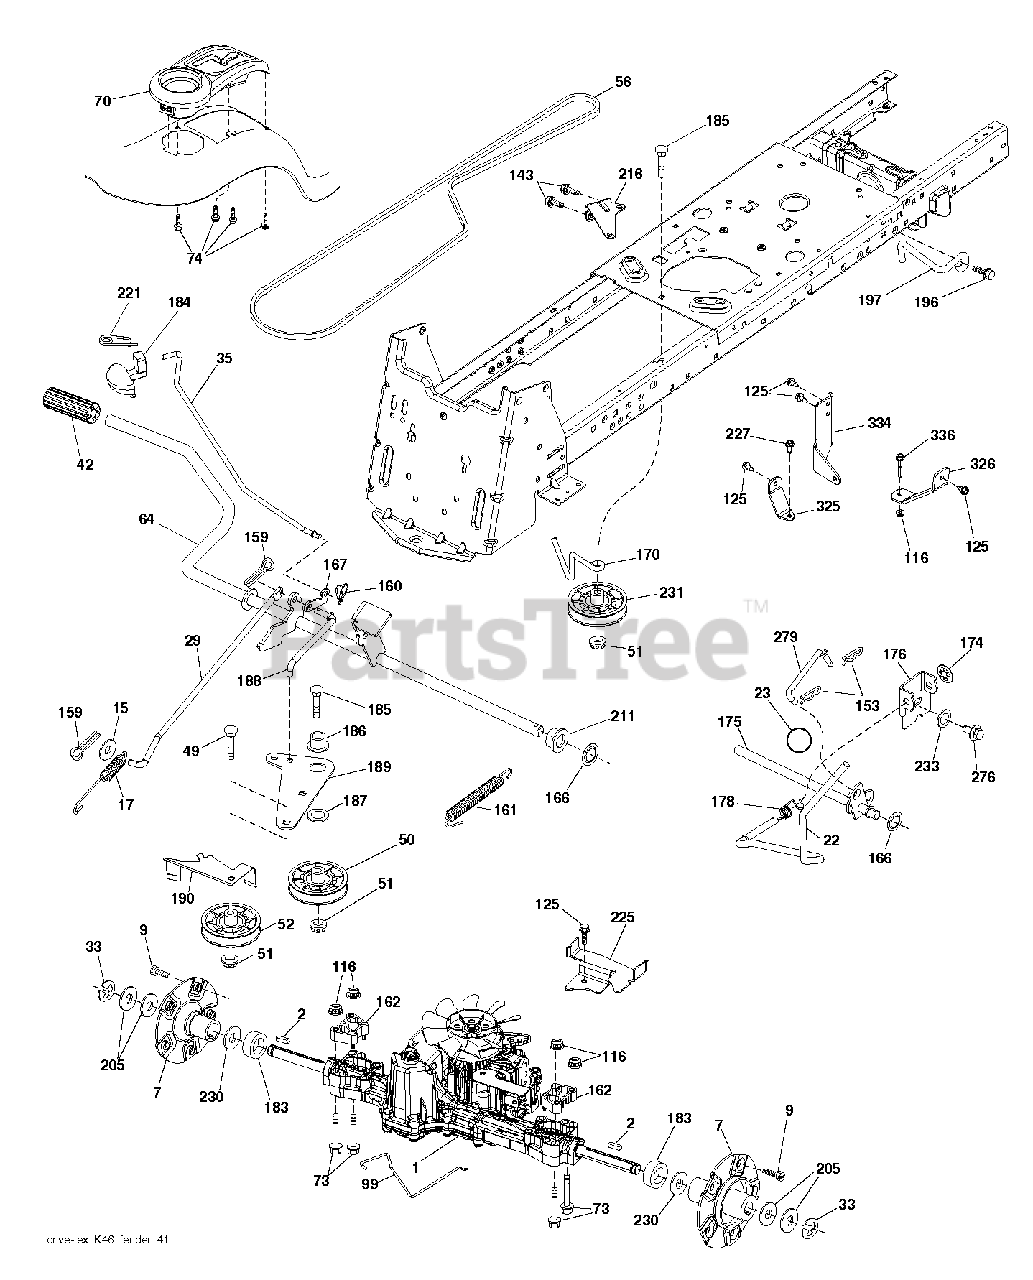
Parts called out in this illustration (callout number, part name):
2	KEY.SQUARE.187X2.500
7	HUB.ASM.WHEEL.REAR.22"
17	SPRING.BRAKE.K46.GREEN
22	ROD.SHIFT.FENDER.STGT.
23	KNOB.DELUXE.(PISTOL.GRIP).BLAC
29	ROD.BRAKE.K46
33	E-RING LT
35	Parking Brake Rod, GT Husq
42	PEDAL COVER T
49	BOLT
50	IDLER.FLAT.910.OFFSET
51	NUT LOCK FLG 3/8-16 UNC
52	IDLER.V-GROOVE.910.OFFSET
64	SHAFT.ASM.PEDAL.BRAKE.
73	BOLT.HEX.FLNG.5/16-18X3.75
74	SCREW.HI-LO.CONSOLE
99	ROD.SPRING.BYPASS.K46.TEX.GT
116	NUT LOCK HEX FLANGE 5/16-18
125	SCREW
153	RETAINER M
159	COTTER PIN
160	RETAINER CLIP
161	SPRING, RETURN LT
162	Transaxle Spacer, 1"
166	NUT.PUSH.625
167	LATCH.BRAKE.SPRING
170	KEEPER.CENTER SPAN.1.688
174	NUT.PUSH.500.2006
175	SHAFT ASM SHIFT
176	ARM.CLEVIS.ROD.SHIFT
178	SPRING.SHIFT.GT2006
183	SPACER.SPLIT.800X.350
184	Parking Brake Handle, Black
186	SPACER.RETAINER
187	WASHER 12/32X2X10GA
188	LINK.CLUTCH.GROUND.DRIVE
189	BELLCRANK.GROUND.DRIVE.TEX.
190	KEEPER.BELLCRANK.DRIVE
196	SCREW 3/8-16X1
197	BRKT.ANIT-ROTATION.CLU
211	BUSHING.SHAFT.BRAKE.HAND
216	BRACKET.PULLEY.IDLER.W/TEX
221	RETAINER.SPRING.CLIP.H
225	KEEPER.BELT.TRANSAXLE.K46
227	SCREW
230	WASHER.HARDENED
231	IDLER.V-GROOVE.1.688.OFFSET
233	WASHER SERRATED
276	BOLT FIN HEX 7/16-14 X 1
279	LINK SHIFT
325	Torque Strap Bracket, 46 22" Tire LH
326	Torque Strap Bracket, 46 22" Tire RH
334	Sway Rod Bracket, K46 X431
336	Flanged Hex Bolt, 5/16-18 X 1-3/4
